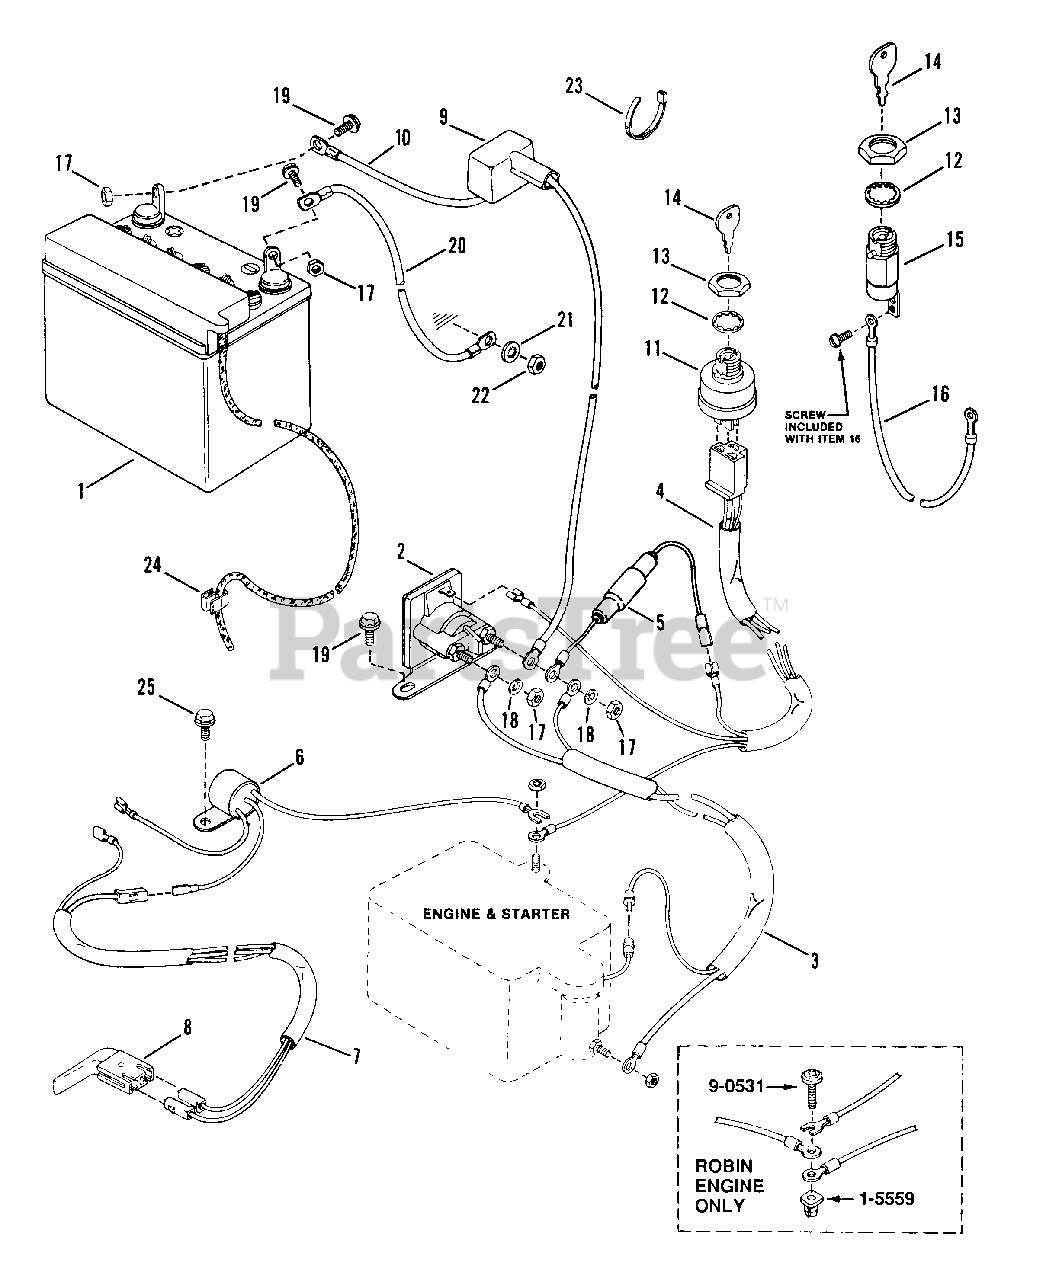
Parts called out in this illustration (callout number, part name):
1	KIT, 12V Dry Charge Battery
2	SOLENOID
3	HARNESS, Starter Wiring
4	HARNESS, Ignition Wiring
5	HOLDER, Fuse
6	INTERLOCK, B&S
6	INTERLOCK, Tec
7	HARNESS, Deck Interlock Wiring
8	SWITCH, Deck Interlock
9	COVER, Battery Cable
10	CABLE, Positive (Red)
10	CABLE, Positive
11	SWITCH, Ignition
12	WASHER, 5/8 Internal Tooth Lock
13	NUT, 5/8-32 Hex
14	KEY, Switch (With Cover)
15	SWITCH, Ignition
16	WIRE, Ground 51.5"
16	GROUND WIRE, Tec Manual Start
17	NUT, 1/4-20 Hex
18	WASHER, 1/4 Internal Tooth Lock
19	SCREW, 1/4-20 x 5/8" Hex Head Cap
20	CABLE, Negative
21	WASHER, 5/16 Internal Tooth Lock
22	NUT, 5/16-18 Hex
23	CABLE-TIE
24	CLIP, Battery Hose
25	SCREW, 1/4-20 x 1/2" Hex Head Self-Tapping
31	SCREW, #10-16 x 1/2" Self-Tapping
32	NUT
